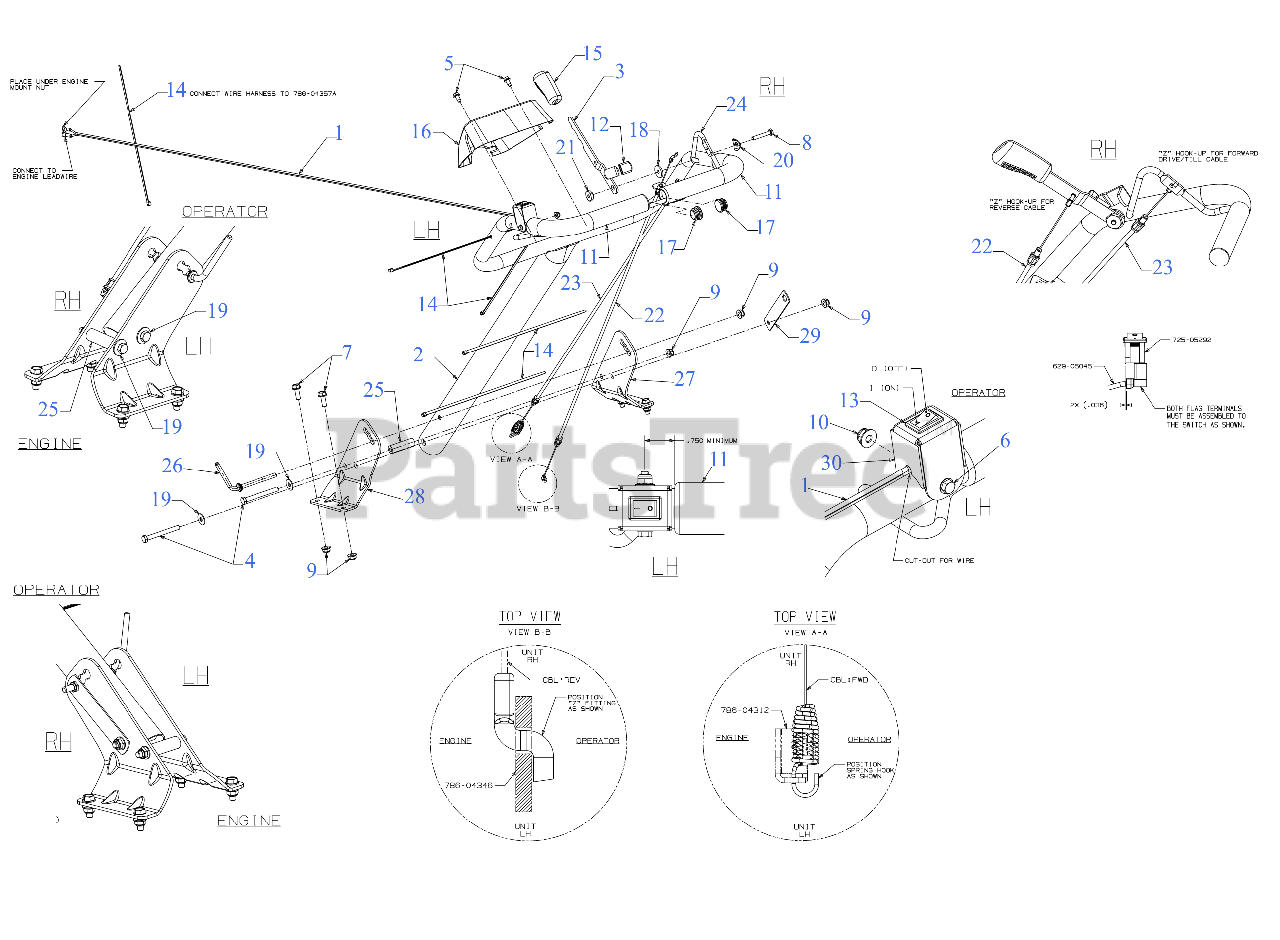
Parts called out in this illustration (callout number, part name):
1	HARNESS ASSEMBLY
4	HEX SCREW 5/16-18 x 3.00
5	SCREW 1/4-20 X.500
6	SCREW HEX HD WASHER (#10-32 x 1.50)
7	SCREW 5/16-18 x .875 GR5
8	BOLT 1/4-20X1.62 GR5
9	FLANGE LOCK NUT 5/16-18
11	FOAM GRIP .970 x 11.0
12	REVERSE HANDLE GRIP
13	POSITIVE SWITCH- ON/OFF
15	BRAKE HANDLE GRIP
16	HANDLE COVER W/O SWITCH HOLE
18	FLAT WASHER
19	BELL WASHER .337 X.867 x .057
20	SADDLE WASHER
21	SHOULDER SPACER
22	REVERSE CABLE
23	FORWARD CABLE
26	CRANK ADJUST HANDLE
29	RETURN BRACKET
30	SWITCH MOUNT BRACKET
